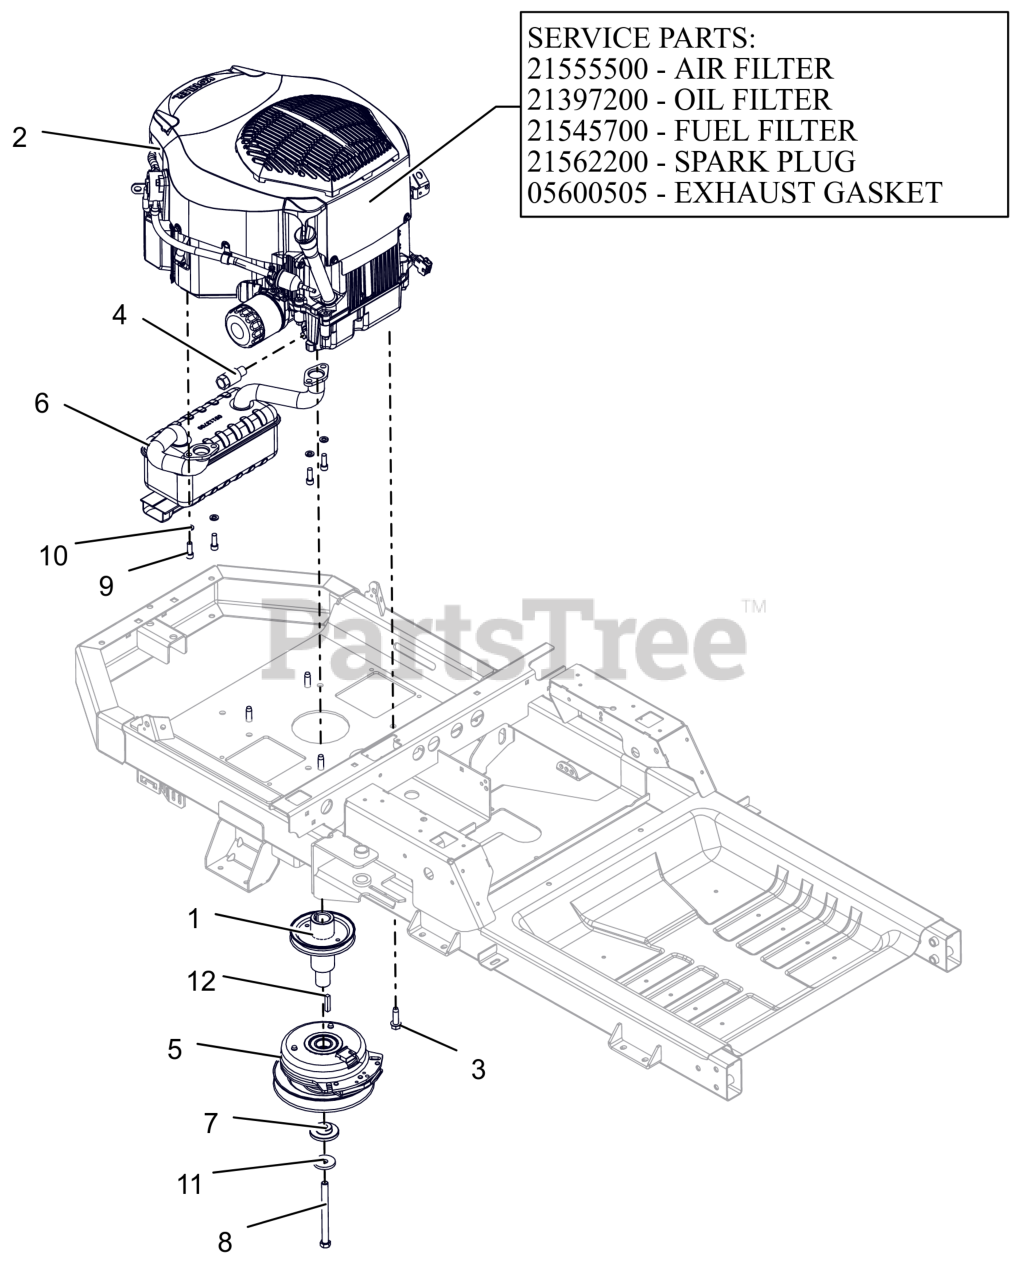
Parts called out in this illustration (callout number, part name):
1	WLDMT, DRIVE SHEAVE (LG XL)CZC
2	ENGINE, KOHLER 24HP TWIN
2	AIR CLEANER, KOHLER
2	FILTER, OIL - KOH CV20
2	FILTER-FUEL KOHLER COURAGE PRO
2	PLUG, SPARK (RFI)
2	GASKET, MUFFLER COURAGE TWIN
3	SCR,TAP .375-16X1.25HWH TR ZCC
4	DRAIN, OIL
5	CLUTCH,105FTLB MONOPOLE 6.83"
6	MUFFLER, KOHLER
7	BSHG-FLG .469X1.06X.574X2.0
8	BLT-HEX.438-20X5 GR8 YZ NYTORQ
9	SCR-CAP .31-18X.88 S/HD G8 ZCC
10	WSHR,LK-REG .312X.078 ZCC
11	WASHER, 7/16" SPRING DISK
12	KEY-SQ .25 X 1.25 X .25 SAE
